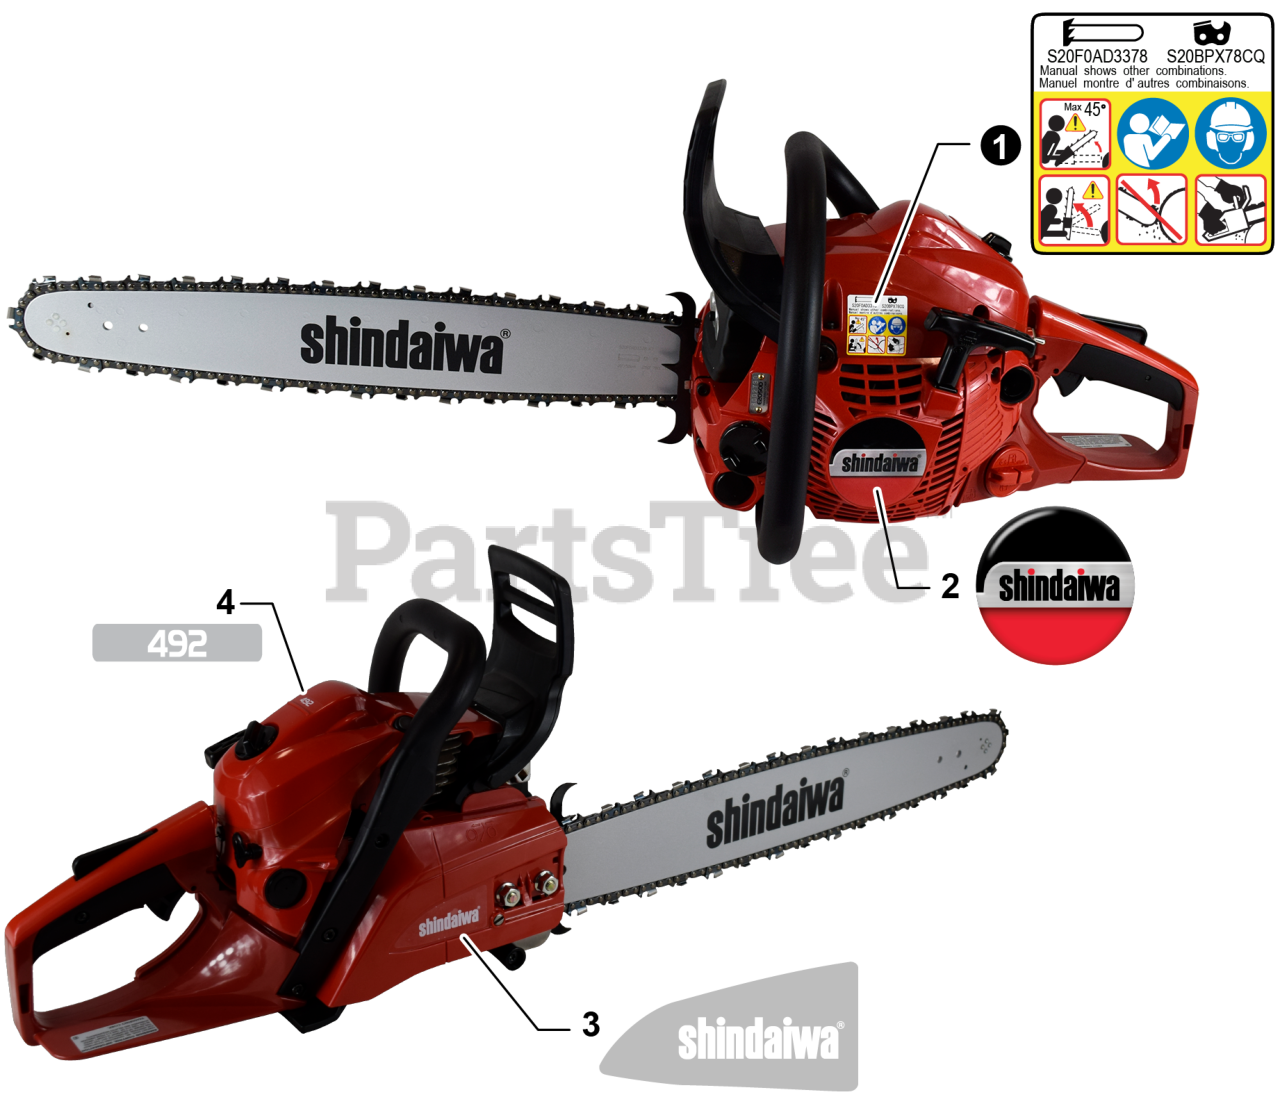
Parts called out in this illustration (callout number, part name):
1	LABEL - CAUTION
2	LABEL - STARTER - SHINDAIWA
3	LABEL - SHINDAIWA
4	LABEL - 492
